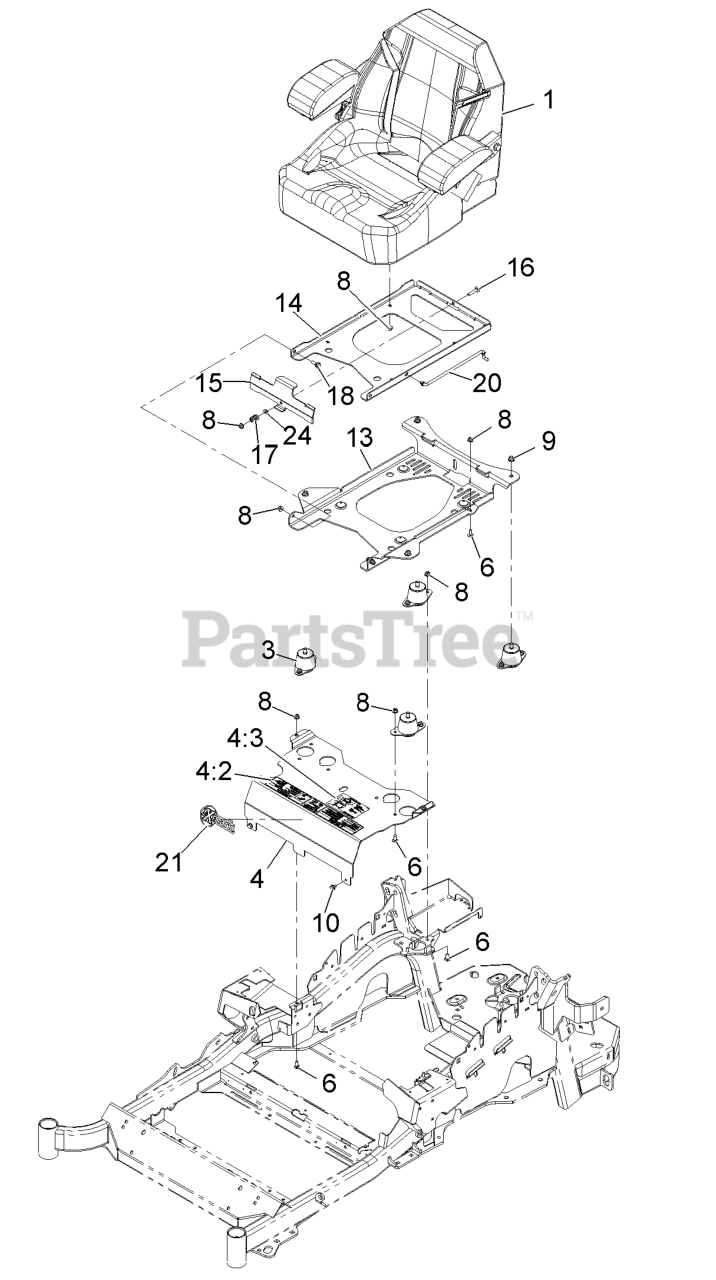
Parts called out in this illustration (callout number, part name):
3	ISOLATOR-SEAT
4	MOUNT-SEAT
4:2	DECAL-CONSOLE
4:3	DECAL-SERVICE AID
6	SCREW-CARR
8	NUT-HF, NI
9	NUT-HF, NI
13	PLATE-SUPPORT, SEAT TILT
14	PLATE-FRAME, SEAT TILT
15	PLATE-LATCH, SEAT
16	BOLT-CARR
17	SPRING-COMPRESSION
18	SCREW-SHOULDER
20	ROD-PROP
24	WASHER-PLAIN
